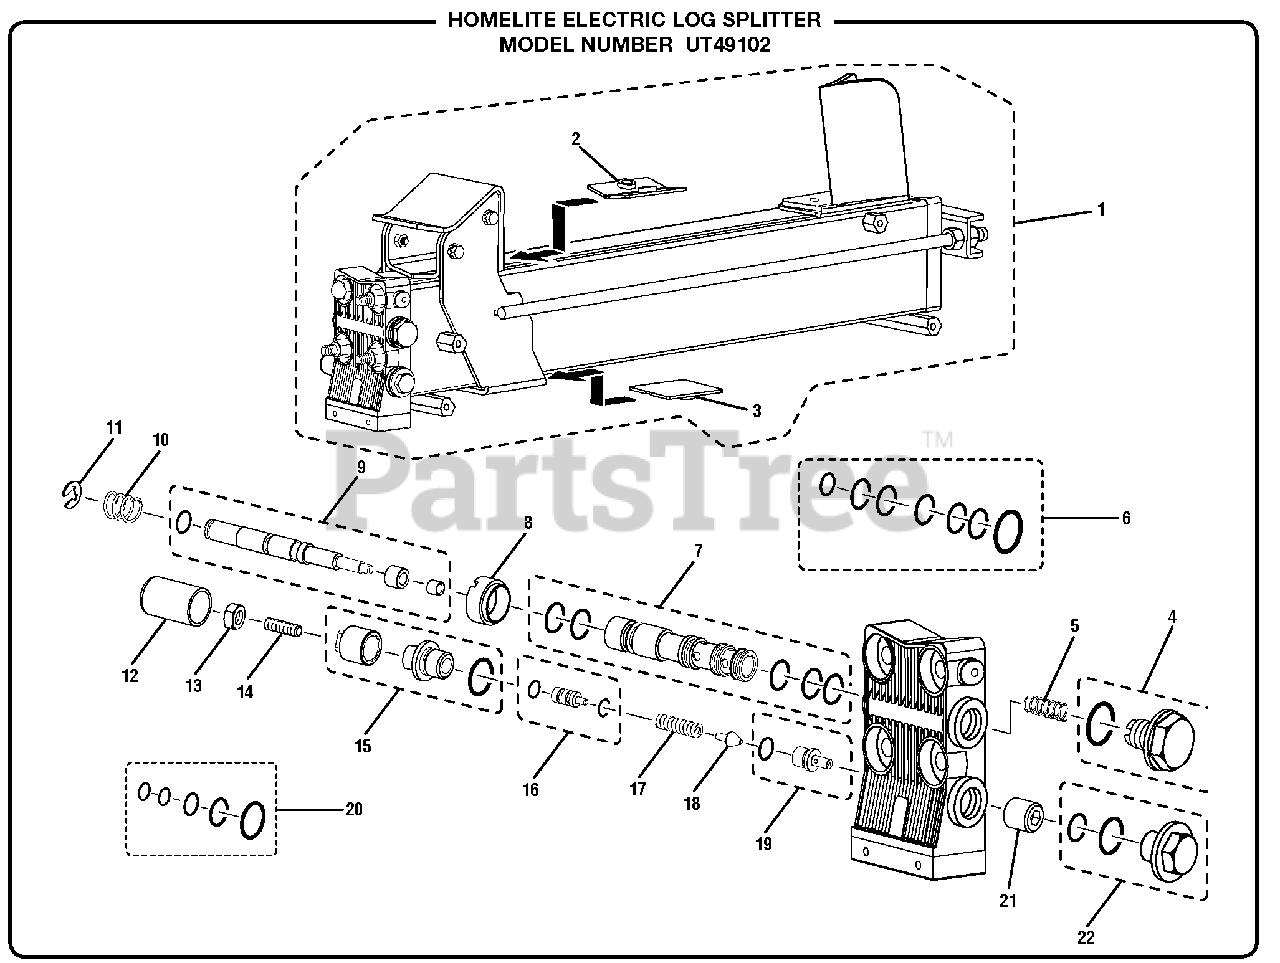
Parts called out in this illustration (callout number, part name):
1	Main Body Assembly
2	Upper Wear Pad
3	Lower Wear Pad
4	Valve Plug Assembly
5	Compression Spring
6	O-ring Kit
7	Valve Body Assembly
8	Valve Body Retainer
9	Valve Assembly
10	Compression Spring
11	Retaining Ring
12	Pressure Relief Valve Cover
14	Pressure Relief Screw (M6 x 20 mm)
15	Relief Valve Bushing Assembly
16	Adjustment Pin Assembly
17	Compression Spring
18	Pressure Relief Valve
19	Relief Valve Seat
20	Pressure Relief Valve O-ring Kit
21	Valve Seat Retainer
22	Pressure Relief Valve Plug Assembly
